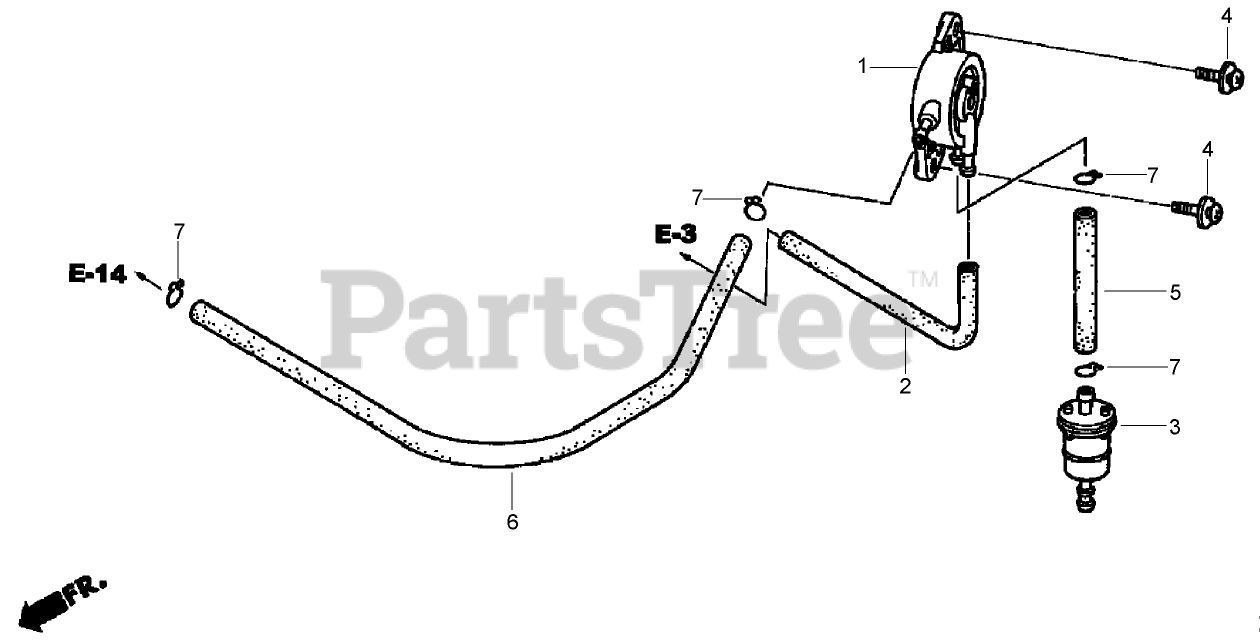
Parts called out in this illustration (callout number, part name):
1	FUEL PUMP ASM
2	TUBE-DIAPHRAGM
3	FILTER-FUEL
4	SCREW-WASHER (5X16)
5	FUEL-HOSE (5.5X8000) (5.5X100)
6	FUEL-HOSE (5.5X8000) (5.5X100)
7	CLIP-TUBE (B10)
